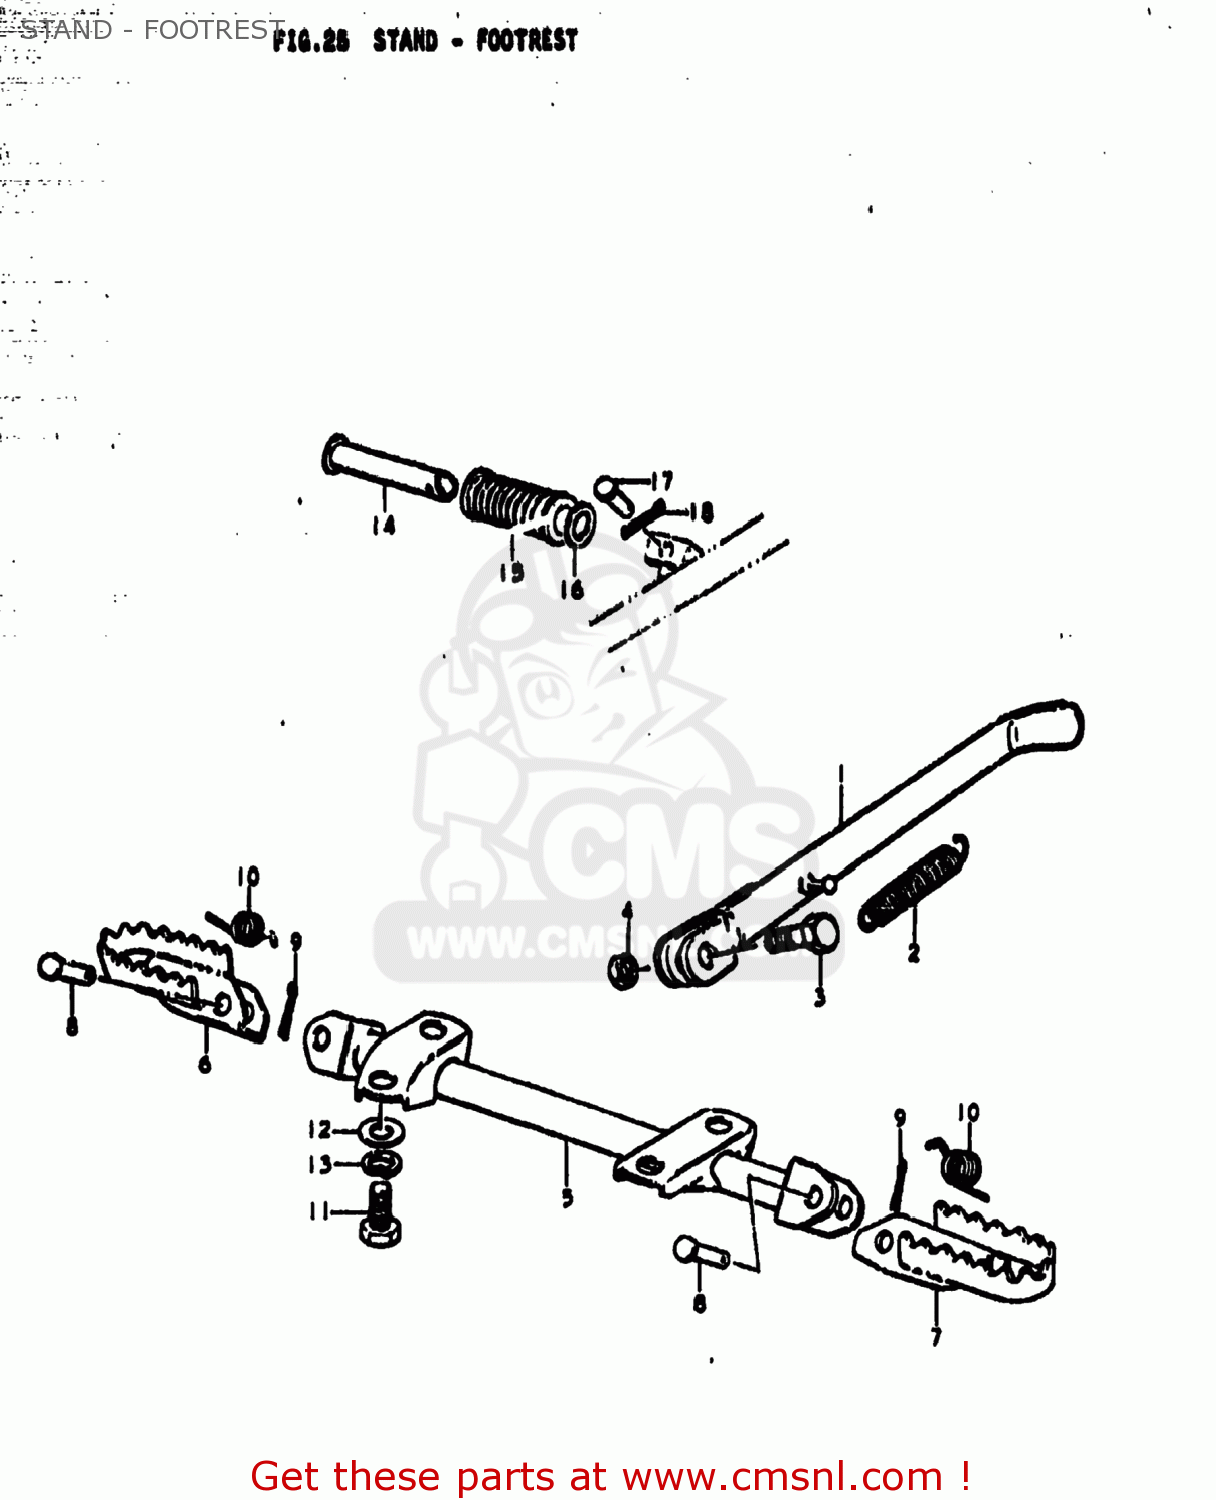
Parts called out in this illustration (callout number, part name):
1	STAND,SIDE
2	SPRING
3	BOLT(10X30)
5	NUT
6	FOOTREST,FR,R
8	PIN
9	PIN 20X20
10	SPRING
11	BOLT
12	WASHER
13	LOCK WASHER
14	BAR,FOOTREST RUBBER
15	RUBBER,PILLION FOOTREST
16	WASHER (19.5X32X2)
17	PIN
18	PIN 20X20
